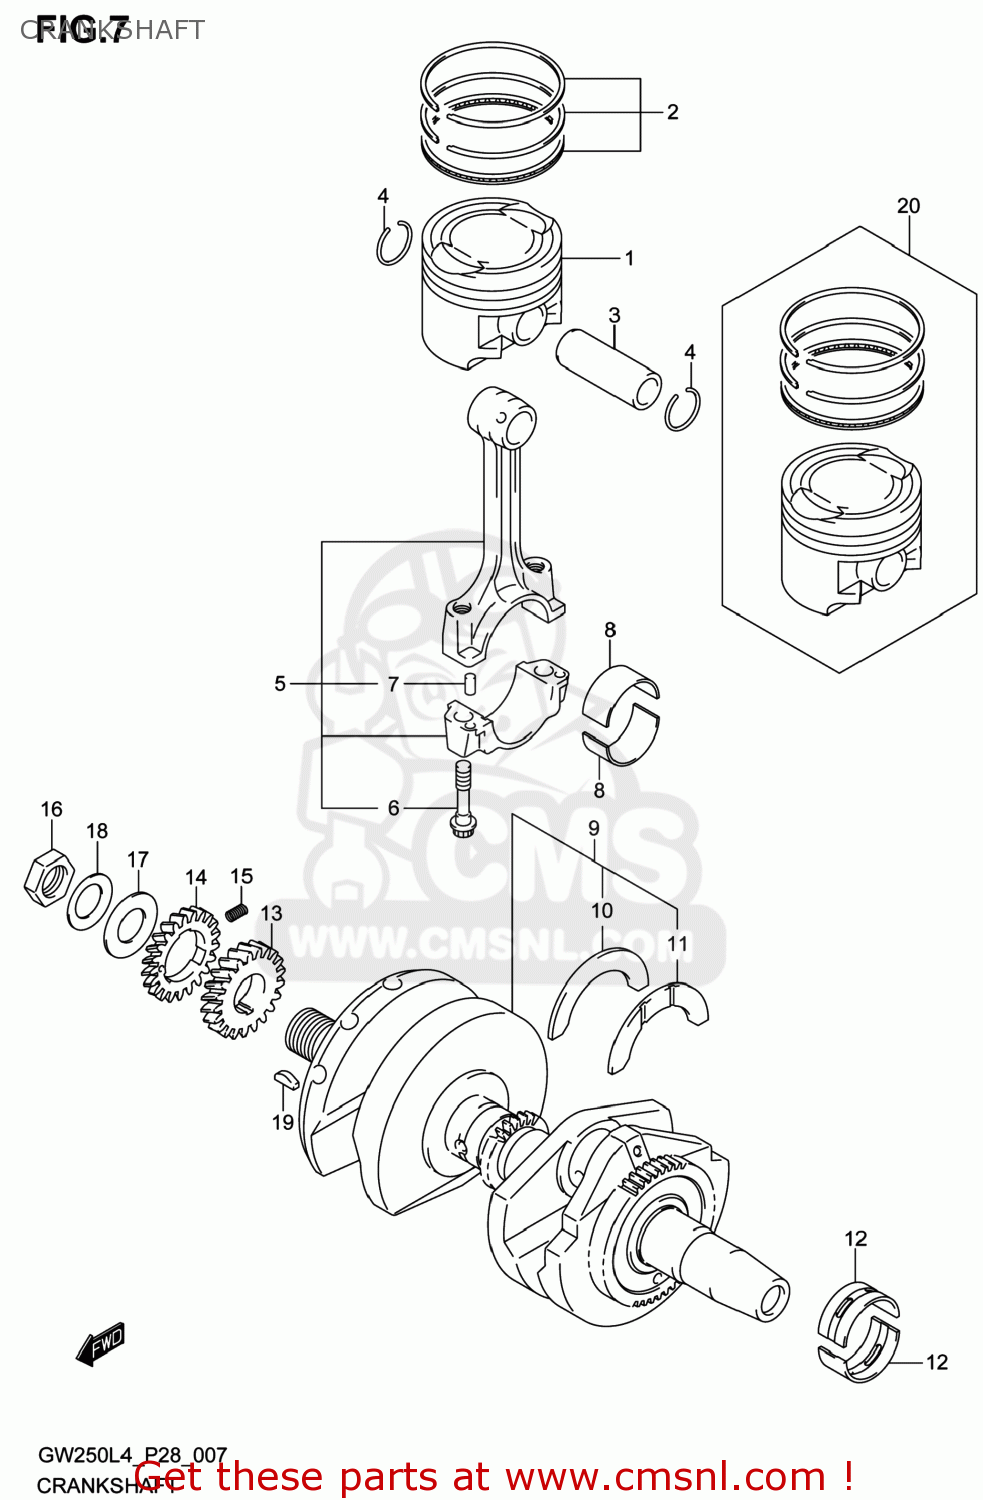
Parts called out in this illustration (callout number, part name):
1	PISTON
2	RING SET,PISTON
3	PIN,PISTON
4	CIRCLIP
5	CONNECTING ROD ASSY
6	BOLT,CONNECTING ROD
7	PIN
8	BEARING,CRANK PIN
9	CRANKSHAFT SET
10	BEARING,CRANK THRUST(YELLOW)
11	BEARING,CRANK THRUST(PINK)
12	BEARING,CRANKSHAFT
13	GEAR,PRIMARY DRIVE
14	GEAR,PRIMARY DRIVE NO.2
15	SPRING,PRIMARY DRIVE GEAR
16	NUT
17	WASHER(18X36X1.5)
18	WASHER
19	KEY
20	PISTON SET(OS:0.5)
